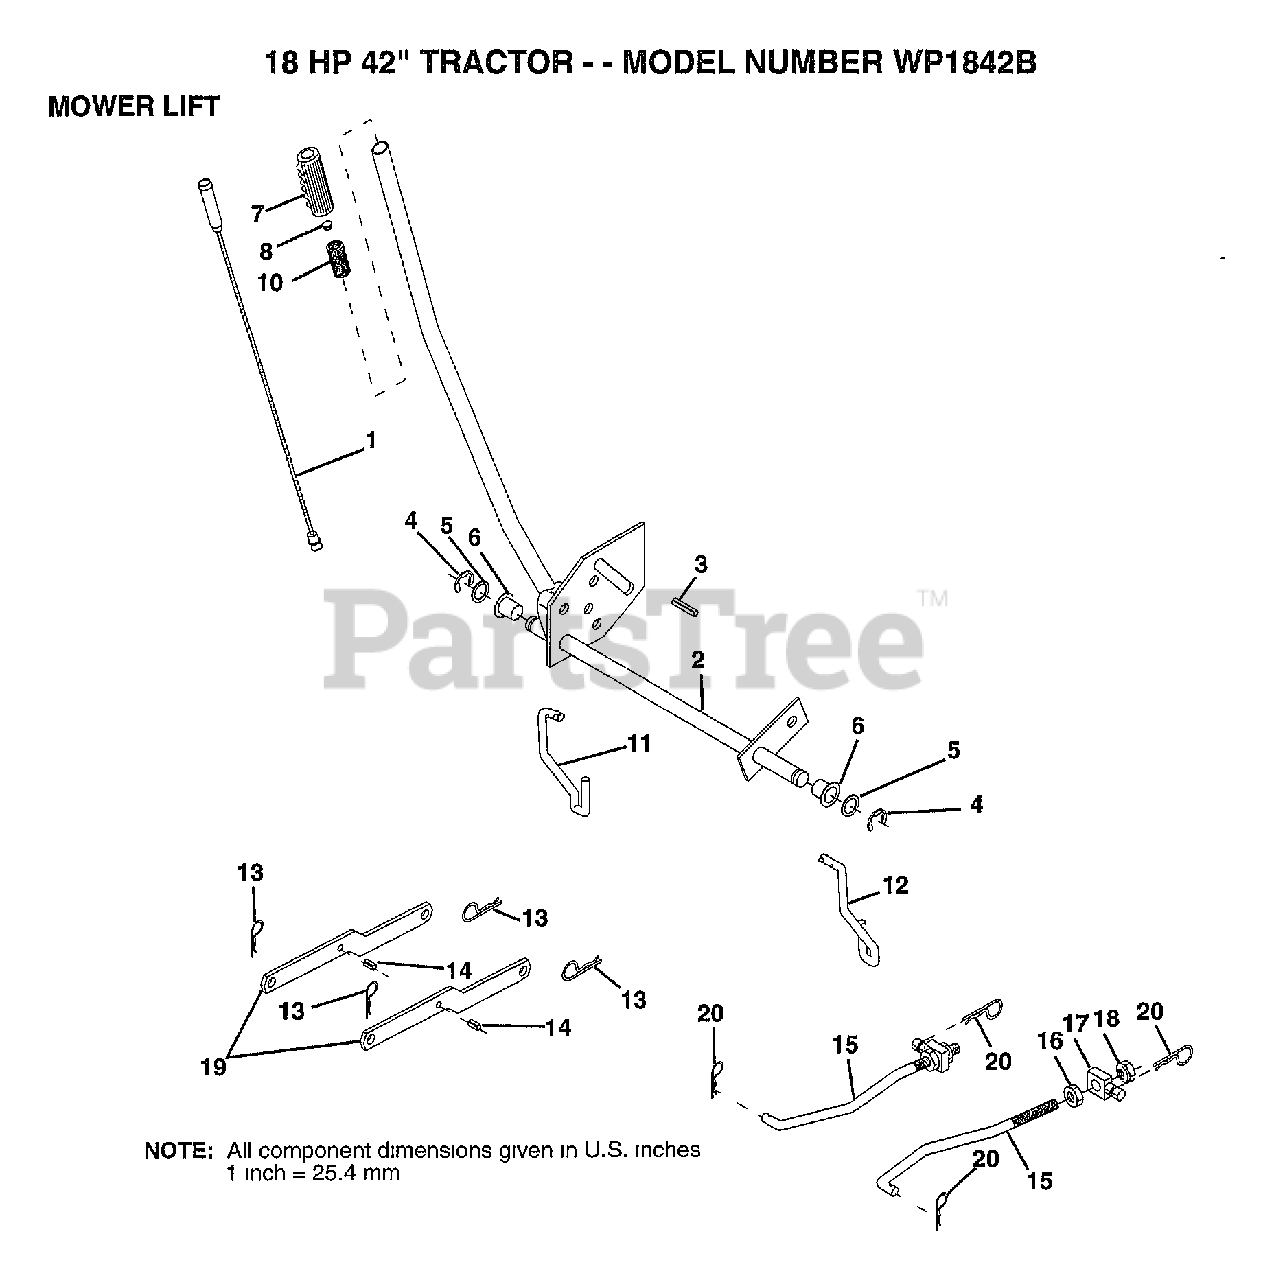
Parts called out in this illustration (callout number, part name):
1	WIRE ASM
2	SHAFT.ASM.LIFT LH
3	PIN GROOVE
5	WASHER
6	NYLON BEARING
7	GRIP
11	LINK LIFT LH
12	LIFT LINK RH
14	"PIN,SPRING"
15	LINK.FRONT
16	NUT
17	TRUNION
18	NUT.LK.W/WSH.1/2.
20	RETAINER.SPRING
